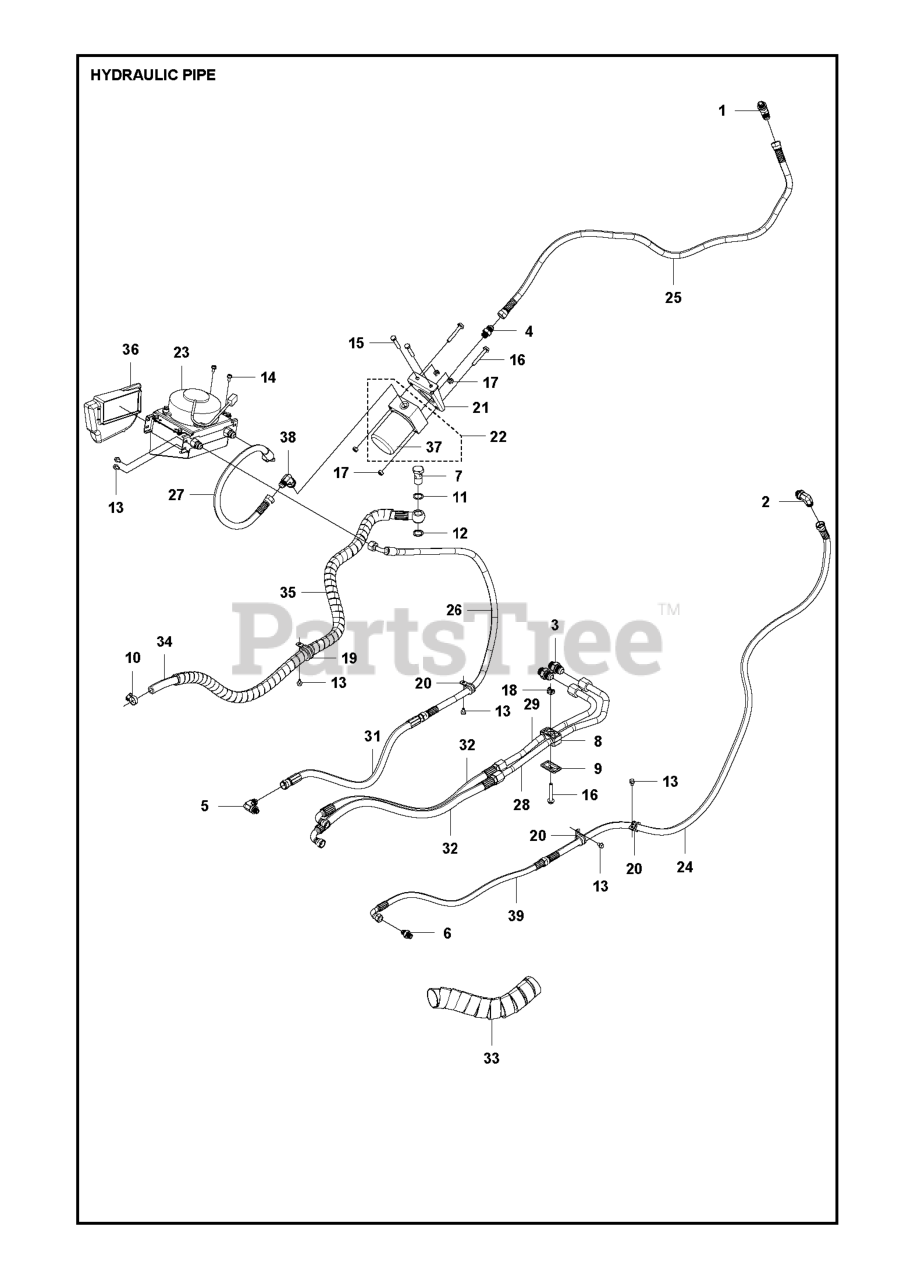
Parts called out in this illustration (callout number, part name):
3	PIPE FITTING
7	PIPE FITTING
8	PIPE CLAMP
9	COVER PLATE
14	SCREW EHHFM
15	SCREW
16	SCREW EHHFM
17	LOCKNUT M8
19	HOSE CLAMP
20	HOSE CLAMP
33	HOSE GUARD D=43 L=400
35	HOSE GUARD
